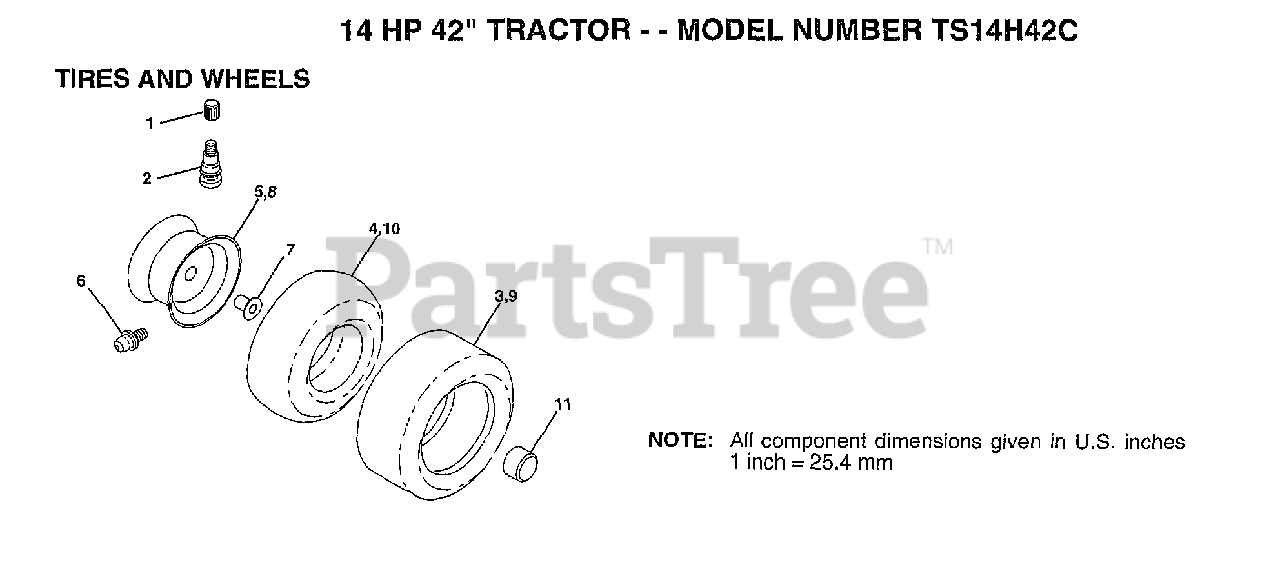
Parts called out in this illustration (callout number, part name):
1	VALVE CAP
2	VALVE STEM LT
4	TUBE.5.3/4.5/6
5	"RIM,FRT T"
6	FITTING LT
7	"FLANGE, BEARING"
8	"RIM 8"""
9	TIRE.20X8-8
10	TUBE.18X9.5-8
11	HUB CAP
